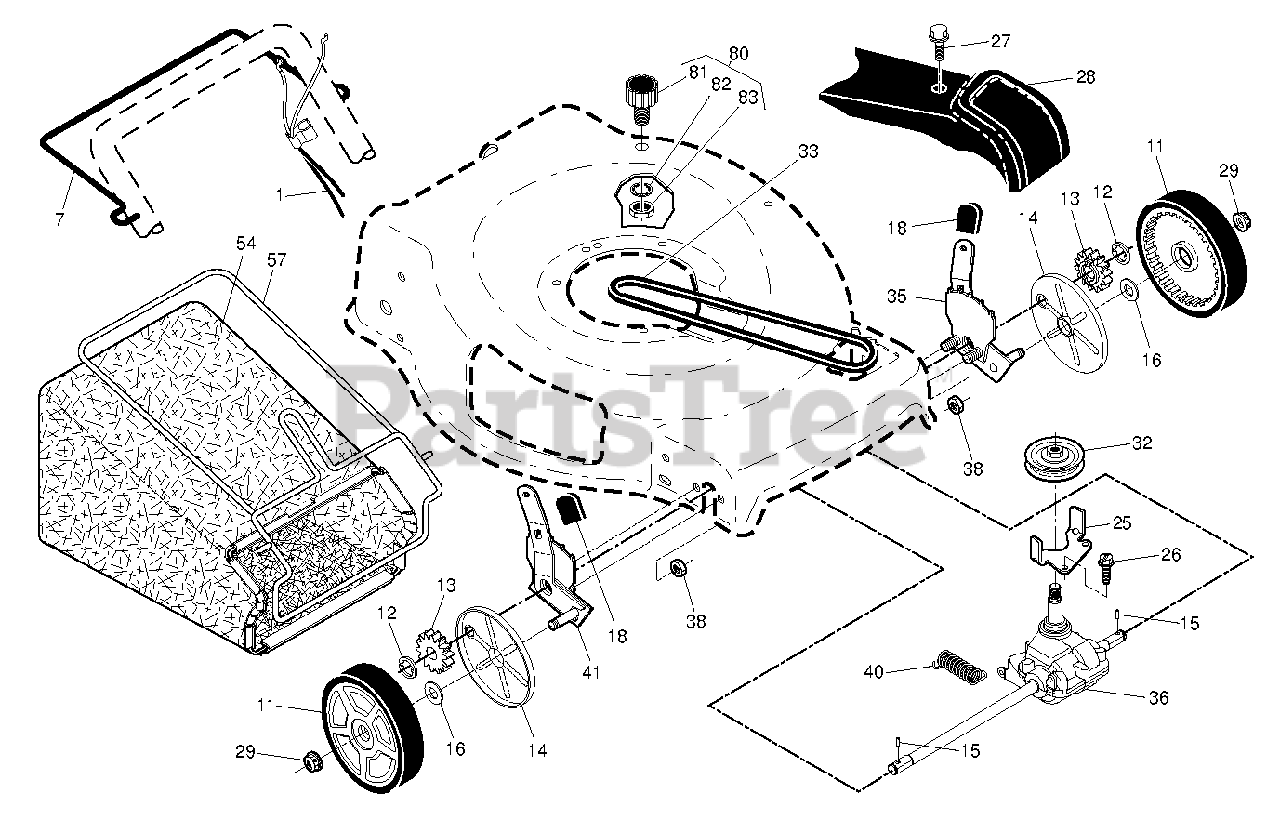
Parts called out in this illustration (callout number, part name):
1	CABLE.DRIV.DUAL.LEVER.BAIL.FGD
7	BAIL.DRIVE.S/S.ROUND.MARI.21
11	WHEEL.8X1.75.5SPK.RAD3.BLACK
12	E-RING 7/16 RE
13	PINION.14.TEETH.FGD
14	COVER.DUST.WHEEL.INNER.WALK
15	PAWL, DRIVE
16	WASHER FLUT
18	SELECTOR KNOB
25	BRACKET.BELT.GUIDE.22+FGD.BZP
27	SCREW, HEX HD TAPPING #10-24 1
28	COVER.DRIVE.22+.MB.GEN.FGD
29	NUT.HEX.FLANGE.3/8-16.LOCKNUT
32	PULLEY.DRIVE.EZ/VARI.SCREWON
33	BELT.DRIVE.FGD.
35	ADJUSTER.ASM.9.22+/RF/LR.21/RF
36	TRANSMISSION.22+.FWGD.SS
38	NUT.HEX.FLANGE.1/4
41	ADJUSTER.ASM.9.22+/RF/LR.21/LF
54	GBAG.A1640416S.BLK.PPRO.MRG.
57	Grass Bag Frame, 22+ Black
80	KIT.WASH-OUT.PORT
81	FITTING, HOSE, WATER WASHOUT
82	WASHER.LOCK.INTERNAL.TOOTH
83	LOCKNUT.HEX.WITH.O-RING
